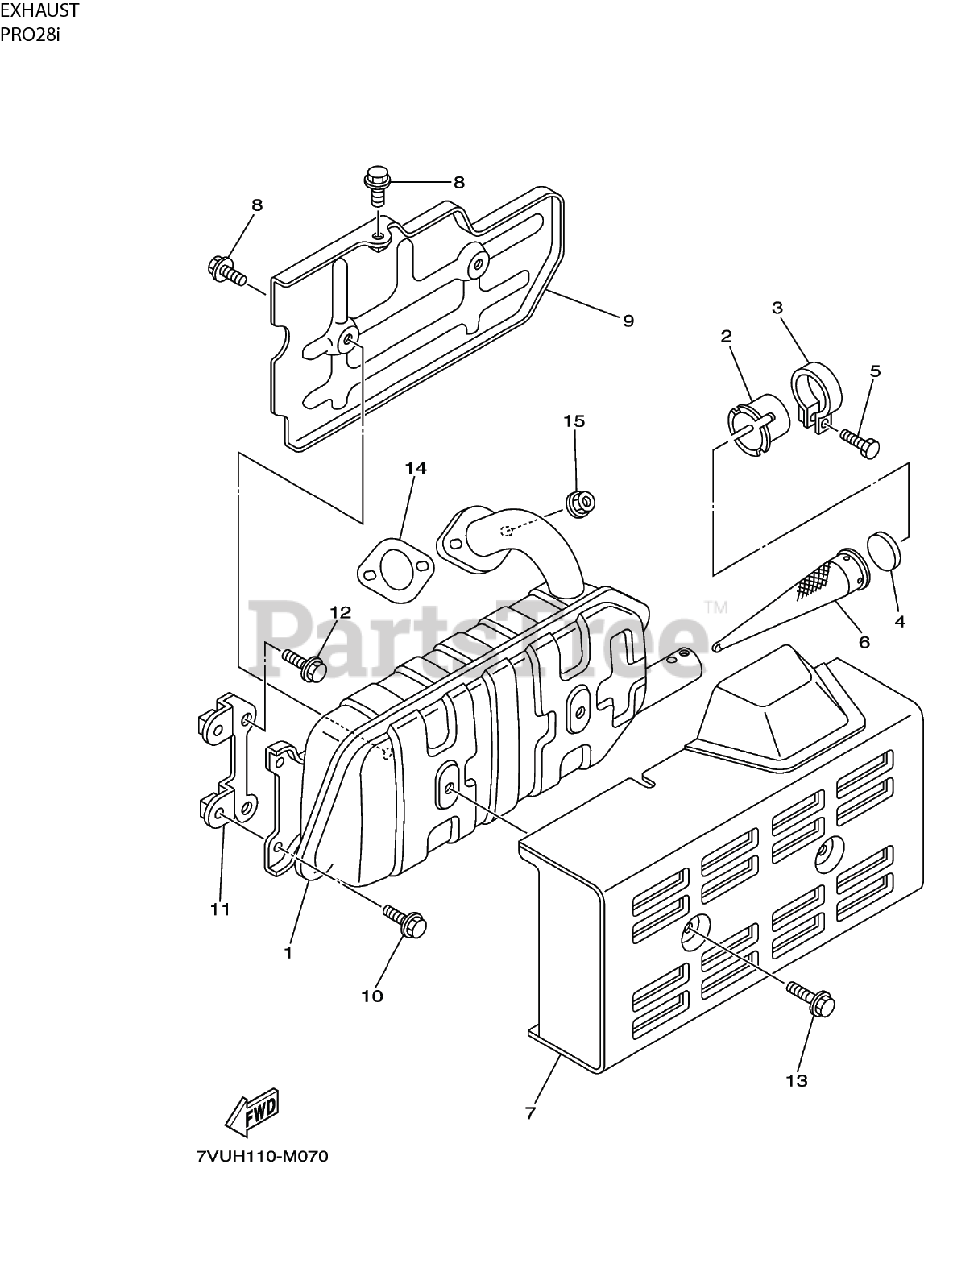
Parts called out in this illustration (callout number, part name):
3	CLAMP - BAND, SILENCER
4	SCREEN - NET, WIRE
5	SCREW - HEXAGON
6	ARRESTER, SPARK
7	GUARD, MUFFLER
8	SCREW - BOLT FLANGE
9	GUARD, MUFFLER
10	SCREW - BOLT FLANGE
11	BRACKET, MUFFLER
12	SCREW - TRUSS HEAD TAPPING
13	SCREW - BOLT FLANGE
14	GASKET, EXHAUST PIPE
